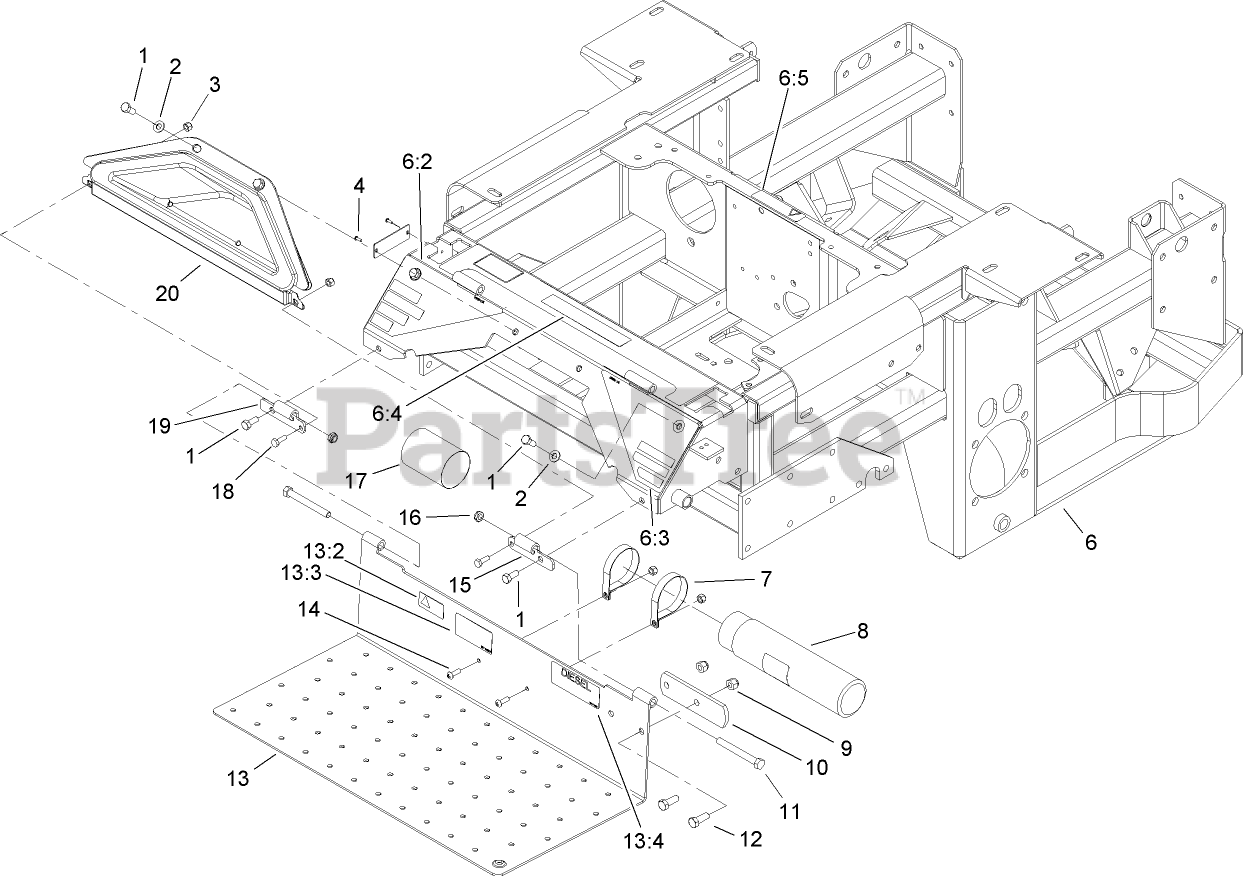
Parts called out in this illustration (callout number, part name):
1	SCREW-HH
2	WASHER-FLAT
3	NUT-LOCK, NI
4	RIVET
6	MAIN FRAME ASM
6:2	Decal-Warning
6:3	Decal-Danger
6:4	DECAL-CONSOLE, TOP
6:5	DECAL-COVER, MISSING
7	R-Clamp
8	TUBE-MANUAL
9	NUT-LOCK, NI
10	STOP-BRAKE, PARK
11	SCREW-HH
12	SCREW-HH
13	FLOOR PAN ASM
13:2	DECAL-PROTECTION, EAR
13:3	Decal-Location, Manual
13:4	DECAL-DIESEL
14	SCREW-PRH
15	Hinge-Floorpan, LH
16	NUT-LOCK, NI
17	CAP-HOUSING
18	SCREW-HH
19	Hinge-Floorpan, RH
20	Pocket
